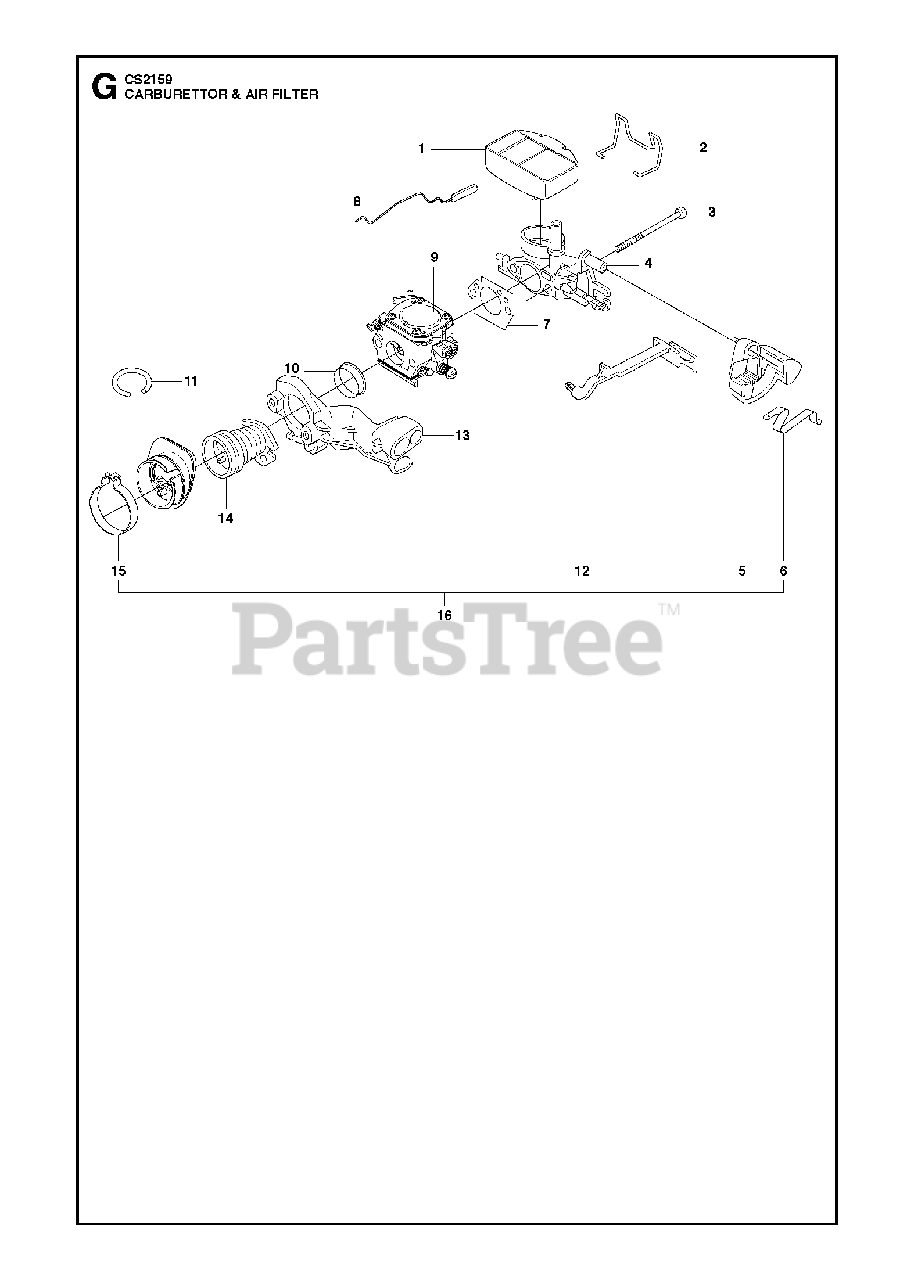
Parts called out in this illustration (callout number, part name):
1	AIR FILTER - NYLON (80)
1	AIR FILTER - NYLON (44)
1	AIR FILTER - FELT
3	SCREW MC6S 5X50
4	FILTER HOLDER
5	CONTROL
6	SPRING
8	THROTTLE ROD
9	RP CARBURETOR
10	SUPPORT RING
11	HOSE, IMPULSE
12	CHOKE CONTROL
15	CLAMP, INTAKE
16	PARTITION WALL INTAKE
